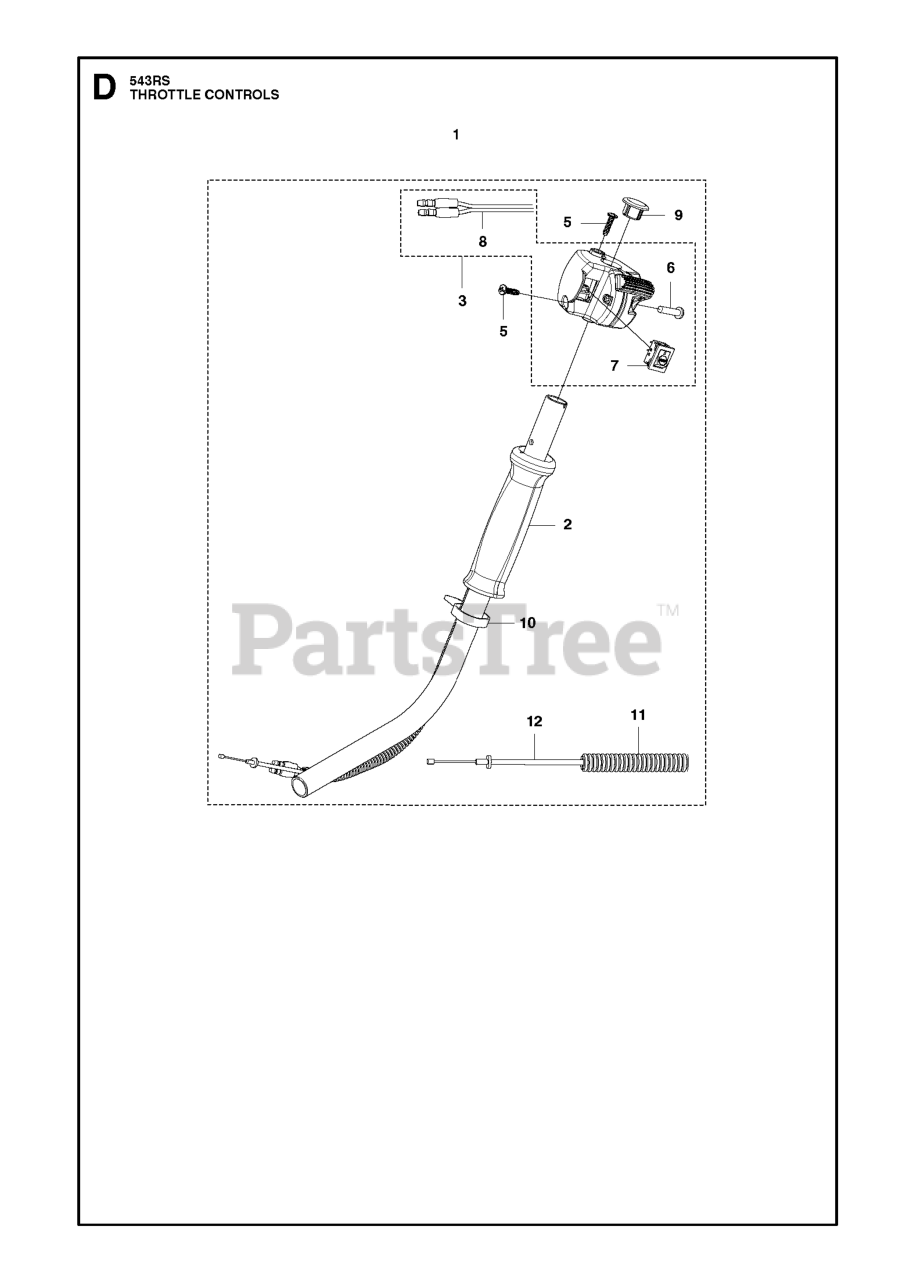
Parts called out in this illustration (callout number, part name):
1	DECAL.FENDER.WARNING.ENGLISH
2	DECAL.BADGE.170MM.TEXTLOGO.
3	DECAL.SDPNL.YT42DXLS.SET
4	DECAL.DECK.6MIL.EURO.NOSTEP
5	DECAL.WARNING.CUST.RESP.E85.
6	DECAL.RPL.KOH.KT7.TLB.42F.K46
7	DECAL.TRACT/ZTR.DECKWARN.HUSQ
9	DECAL BTRY SYMBOLS
11	DECAL.HV.REINFORCED.DECKS.2012
12	DECAL.V-BELT.SCH.42/46"MEC/ELE
